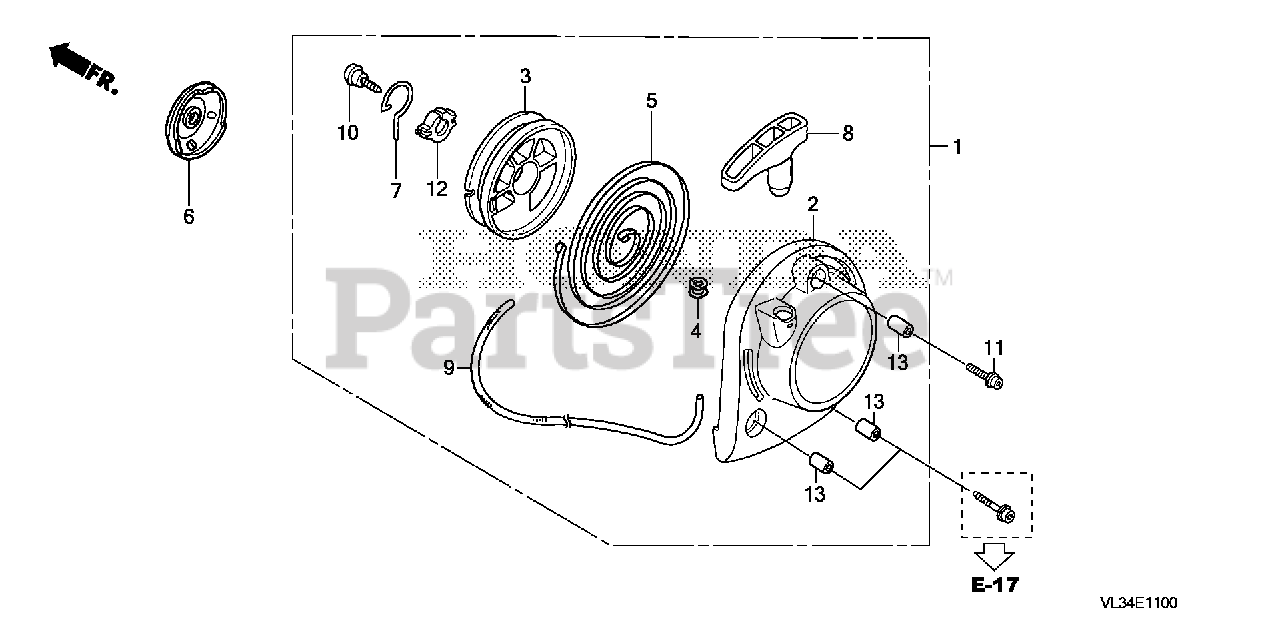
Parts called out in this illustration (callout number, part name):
1	STARTER ASSY., RECOIL
2	CASE, RECOIL STARTER
3	REEL, RECOIL STARTER
4	GUIDE, ROPE
5	SPRING, RECOIL STARTER
6	PULLEY, RECOIL STARTER
8	KNOB, RECOIL STARTER
9	ROPE, RECOIL STARTER (#3.5X40")
10	SCREW, SETTING
11	BOLT, SOCKET (5X16)
13	COLLAR A, HEAD COVER
